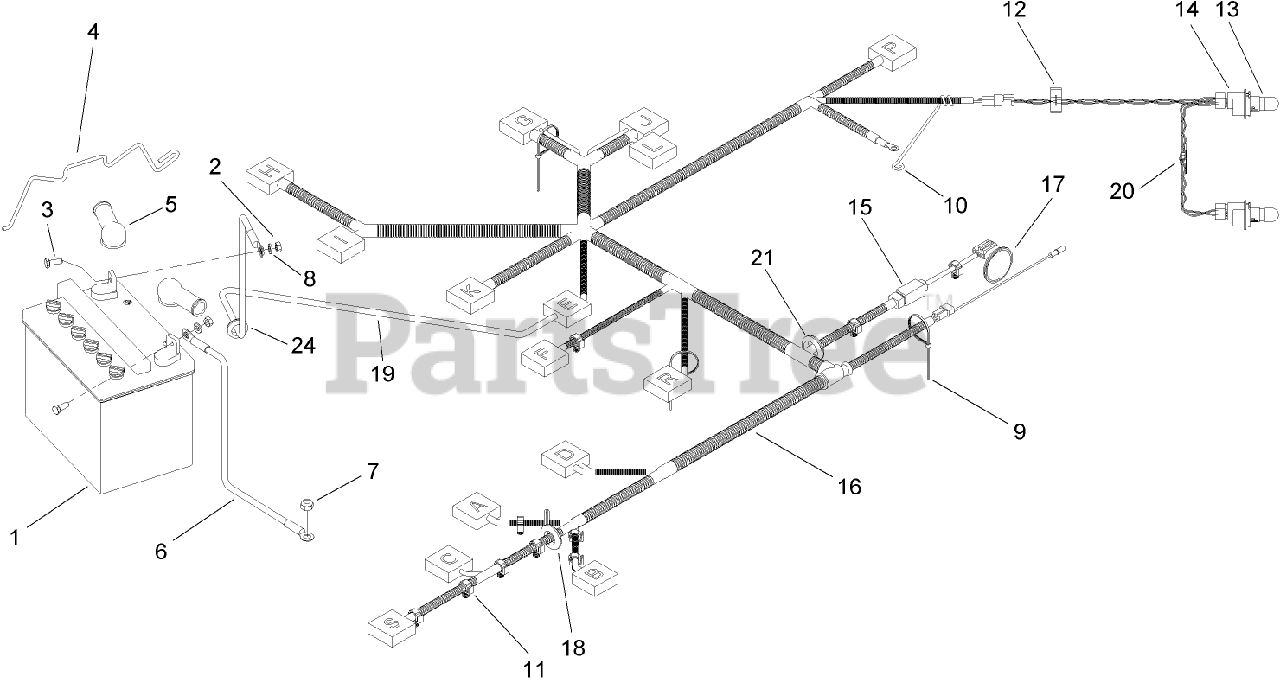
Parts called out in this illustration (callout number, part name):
1	BATTERY-12V
2	NUT-HEX
3	SCREW-HH
4	CLAMP-BATTERY
5	BOOT-RUBBER
6	CABLE-BATTERY, Negative
7	NUT-LOCK, NI
8	WASHER-FLAT
9	TIE-CABLE
10	HOLDER-HARNESS, WIRING
11	CLIP-SNAP
12	HARNESS-WIRE, LIGHTS
13	BULB-LIGHT
15	HARNESS-CLUTCH
16	HARNESS-WIRING
18	BUSHING
20	CLIP-NYLON
24	GROMMET
